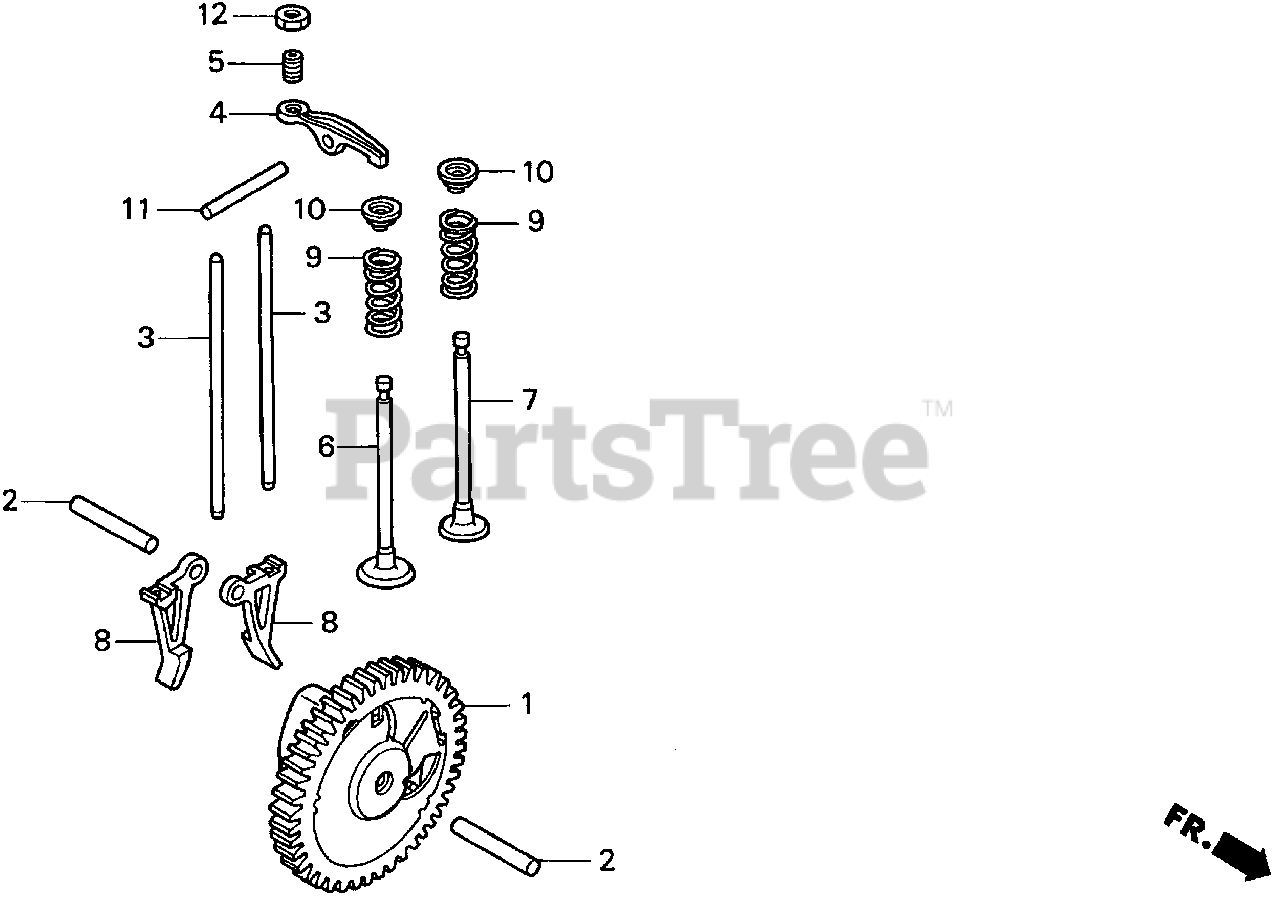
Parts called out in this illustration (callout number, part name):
1	CAMSHAFT ASSY.
2	ROLLER (5X23.8)
3	ROD, PUSH
4	ARM, VALVE ROCKER
5	PIVOT, ROCKER ARM
6	VALVE, IN.
7	VALVE, EX.
8	LIFTER, VALVE
9	SPRING, VALVE
10	RETAINER, VALVE SPRING
11	ROLLER (4X28)
12	NUT, TAPPET ADJUSTING
